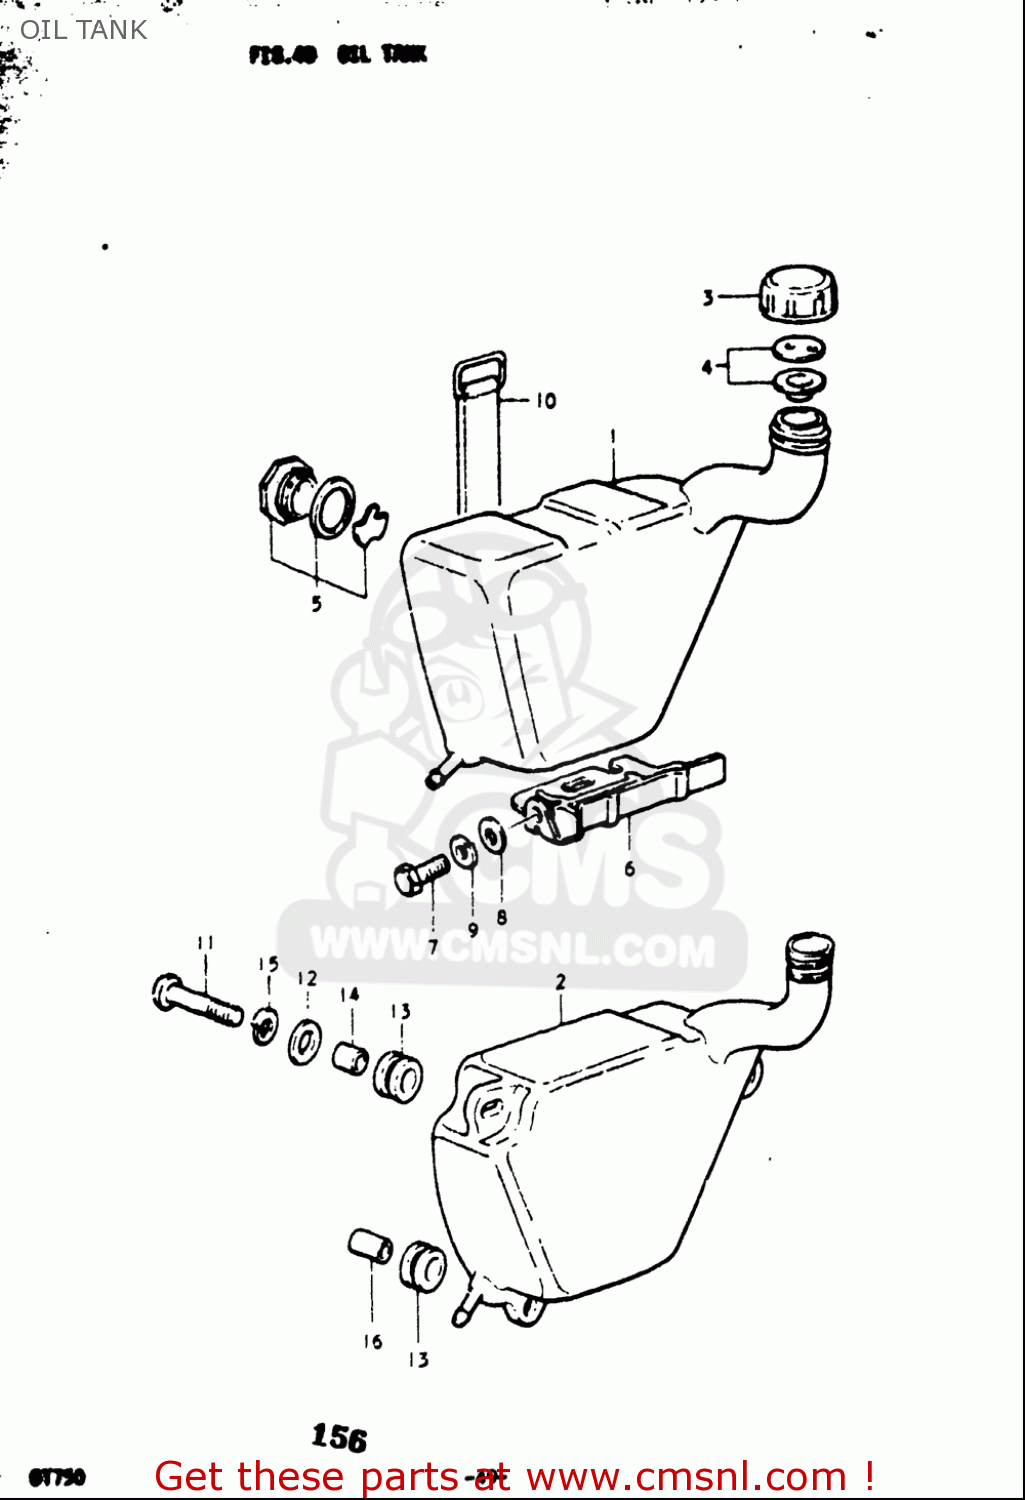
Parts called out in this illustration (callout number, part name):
3	CAP,OIL TANK
4	GASKET SET (NAS)
5	LENS SET,OIL LEVEL
7	BOLT
8	WASHER
9	WASHER,LOCK
10	BAND
11	SCREW
12	WASHER(6.5X18X1.6)
13	CUSHION
14	SPACER(6.5X10X10)
15	WASHER,LOCK
16	SPACER(6.8X10X24.2)
